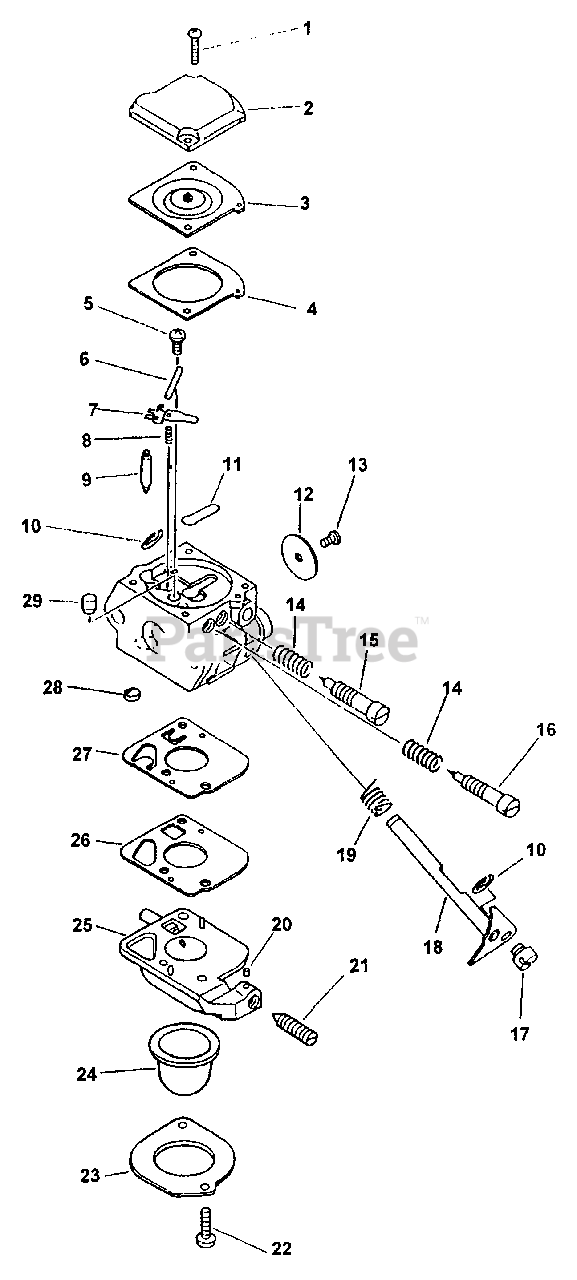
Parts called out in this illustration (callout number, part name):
2	COVER, DIAPHRAGM
3	DIAPHRAGM, METERING
4	GASKET, METERING
6	PIN, METERING LEVER
7	LEVER, METERING
8	SPRING, METERING LEVER
9	VALVE, INLET NEEDLE
11	PLUG, WELCH
12	VALVE, THROTTLE
13	SCREW 3×4.5
14	SPRING, NEEDLE
15	NEEDLE, IDLE
16	NEEDLE, HIGH SPEED
18	SHAFT, THROTTLE
19	SPRING, THROTTLE RETURN
20	PIECE, FRICTION
21	SCREW, IDLE ADJUST
23	RETAINER
24	BULB, PURGE
25	BODY ASSY, PURGE
28	STRAINER
29	NOZZLE, CHECK VALVE
